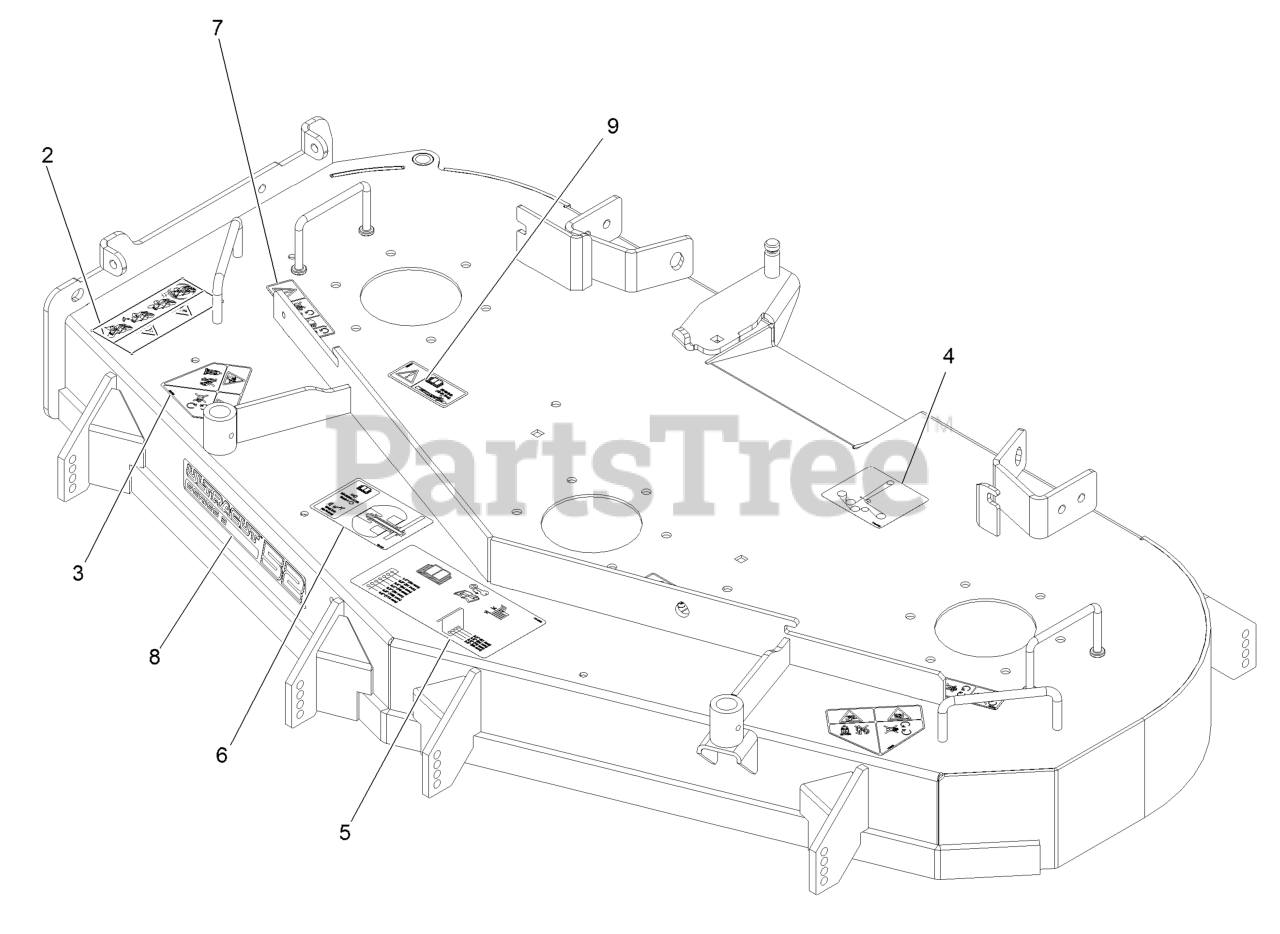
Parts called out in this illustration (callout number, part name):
2	DECAL-WARNING, BAGGER
3	DECAL-DANGER
4	DECAL-BELT ROUTING
5	DECAL-ANTI-SCALP
6	DECAL-ROLLER MOUNTING
7	DECAL-COVER, MISSING
8	DECAL-ULTRACUT 52 SERIES
9	DECAL-BOLT TORQUE
